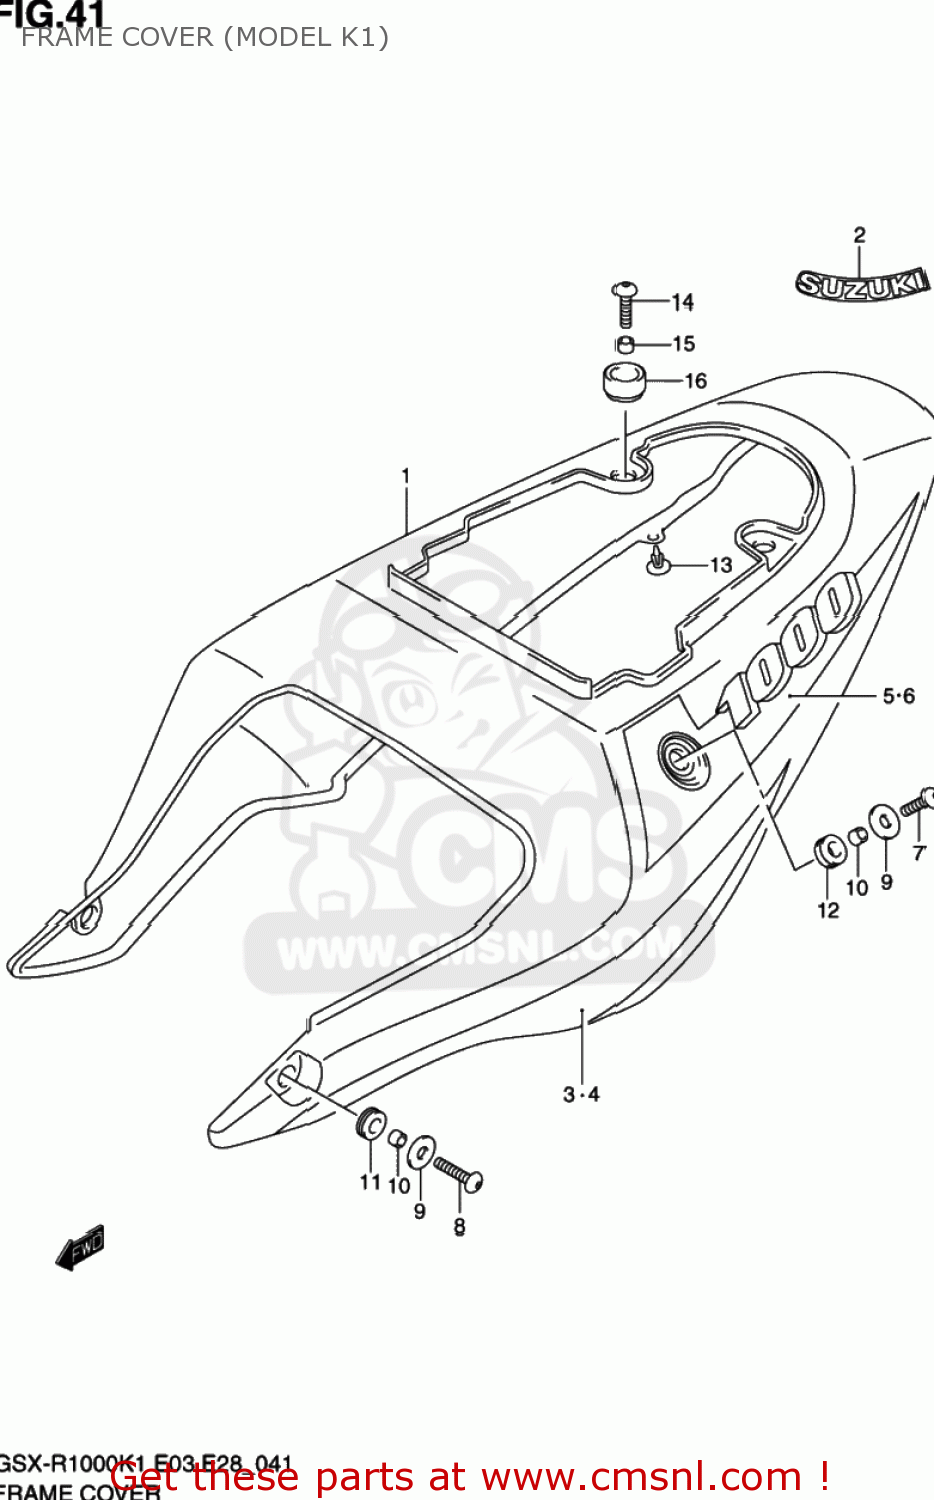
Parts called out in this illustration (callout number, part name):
1	COVER ASSY,FRAME(BLACK)
2	EMBLEM,FRAME COVER
3	TAPE,FRAME COVER STRIPE,R
4	TAPE,FRAME COVER STRIPE,L
5	TAPE,FRAME COVER,R
6	TAPE,FRAME COVER,L
7	SCREW(6X25)
8	SCREW(6X30)
9	WASHER(6.5X20X2)
10	SPACER(6.5X10X7)
11	CUSHION,FRAME COVER FR
12	CUSHION,FRAME COVER SIDE
13	CLIP(BLACK)
14	SCREW(6X25)
15	SPACER(6.5X10X9.4)
16	CUSHION
